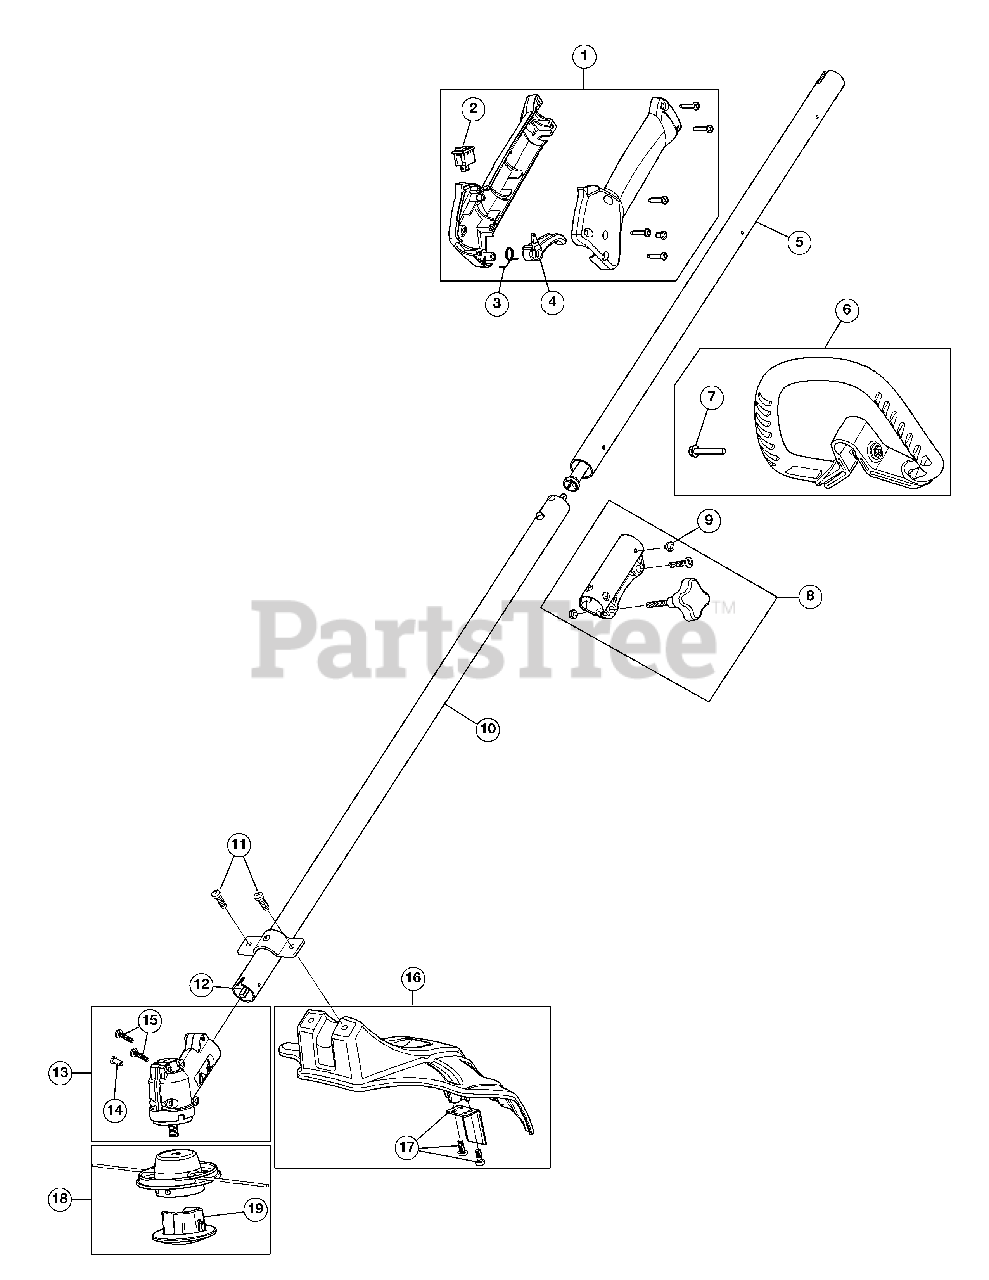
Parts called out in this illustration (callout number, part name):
1	Throttle Housing Assembly (Incl. 2 - 4)
2	Trigger Switch Assembly
3	Throttle Trigger Spring
4	Throttle Trigger
5	Upper Drive Shaft Assembly
6	D-Handle Assembly (Incl. 7)
8	Split Boom Coupler (Incl. 9)
9	Coupler Anti-Rotation Screw
10	Lower Drive Shaft Housing
11	Shield Mounting Screws
12	Lower Flexible Drive Shaft
13	Gearbox Assembly (Incl. 14 and 15)
14	Gearbox Anti-Rotation Screw
15	Gearbox Mounting Hardware
16	Shield Assembly (Incl. 17)
17	Blade Assembly
18	Cutting Head Assembly (Incl. 19)
19	Cutting Head Cap
